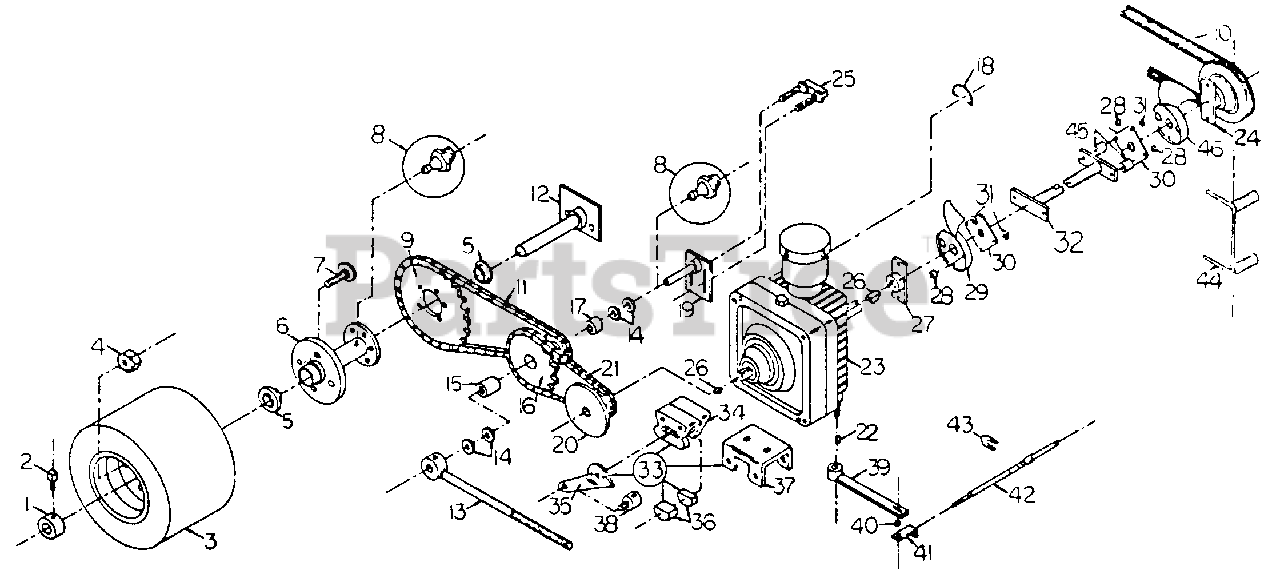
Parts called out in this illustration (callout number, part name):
1	Set Collar, l"
2	Squarehead Setscrew, 5/16-18 x 1/2"
3	Drive Wheel Ass'y., 16 x 7.50-8
4	Lug Nut, 1/2-20
5	Drive Wheel Bearing
6	Drive Wheel Hub
7	Lug Bolt, 1/2-20 x 1 1/4"
8	Self-tapping Zerk, 1/4-28
9	Final Drive Sprocket, 40A 54
10	Transmission Belt
11	Final Drive Chain
12	Drive Wheel Axle
13	Support Collar
14	Machine Washer, 3/4", 10 GA
15	Idler Sprocket Bearing, 1/2"
16	Idler Sprocket
17	Idler Sprocket Bearing, 3/4"
18	Transmission Dump Valve Clip
19	Idler Sprocket Shaft
20	Transmission Sprocket w/Brake Disc
21	Primary Drive Chain
22	Woodruff Key, 1/8" x 3/8"
23	Transmisslon, LH
24	Pulley w/Drive Plate
26	Woodruff Key, 1/8" x. 1/2"
27	Hub w/Drive Plate
30	Drive Plate
31	Washer, 1/4", 10 GA
33	Brake Assembly, LH
34	Brake Caliper
35	Caliper Lever, LH
36	Brake Pad
37	Caliper Bracket
38	Caliper Rod Collar
39	Transmission Arm, LH
40	Cable End Bushing
41	Steering Cable End
42	Steering Cable
43	Steering Cable Clamp
44	Transmission Belt Retainer
